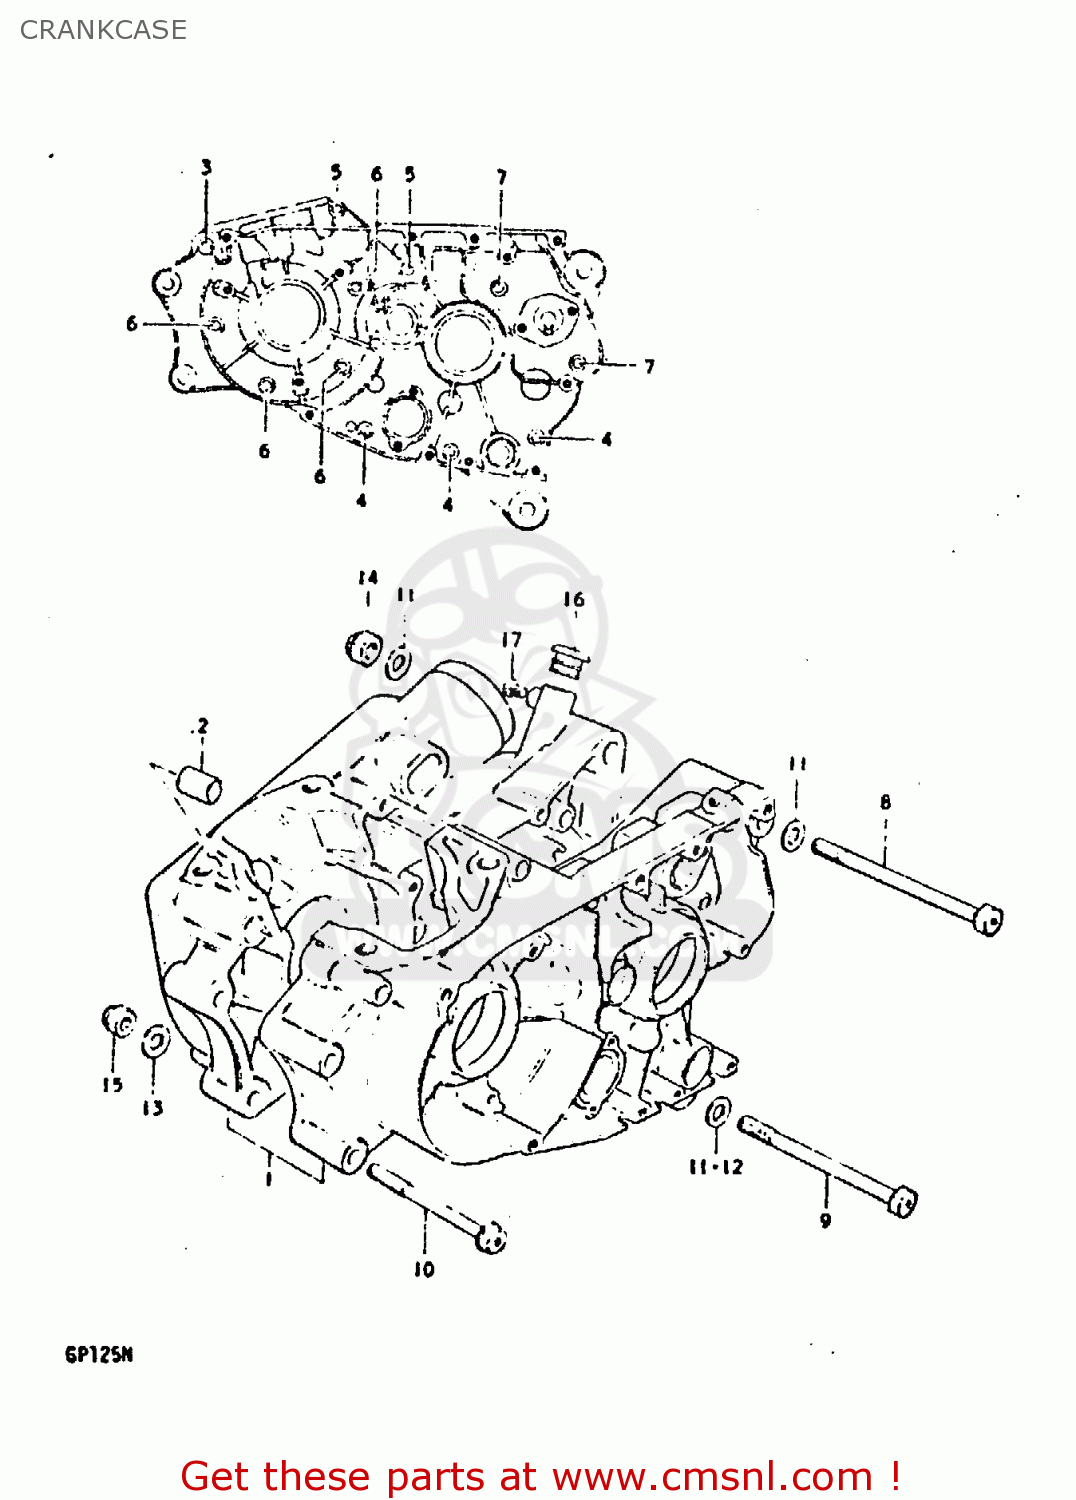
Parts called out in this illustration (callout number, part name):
1	CRANKCASE SET
2	PIN
3	SCREW 6X70
4	SCREW 6X65
5	SCREW
6	SCREW
7	SCREW (6X35)
8	BOLT 10X120
9	BOLT 10X115
10	BOLT 8X90
11	WASHER
12	WASHER(10.5X20X3.2)
14	NUT
15	NUT
16	Plug
17	BOLT
